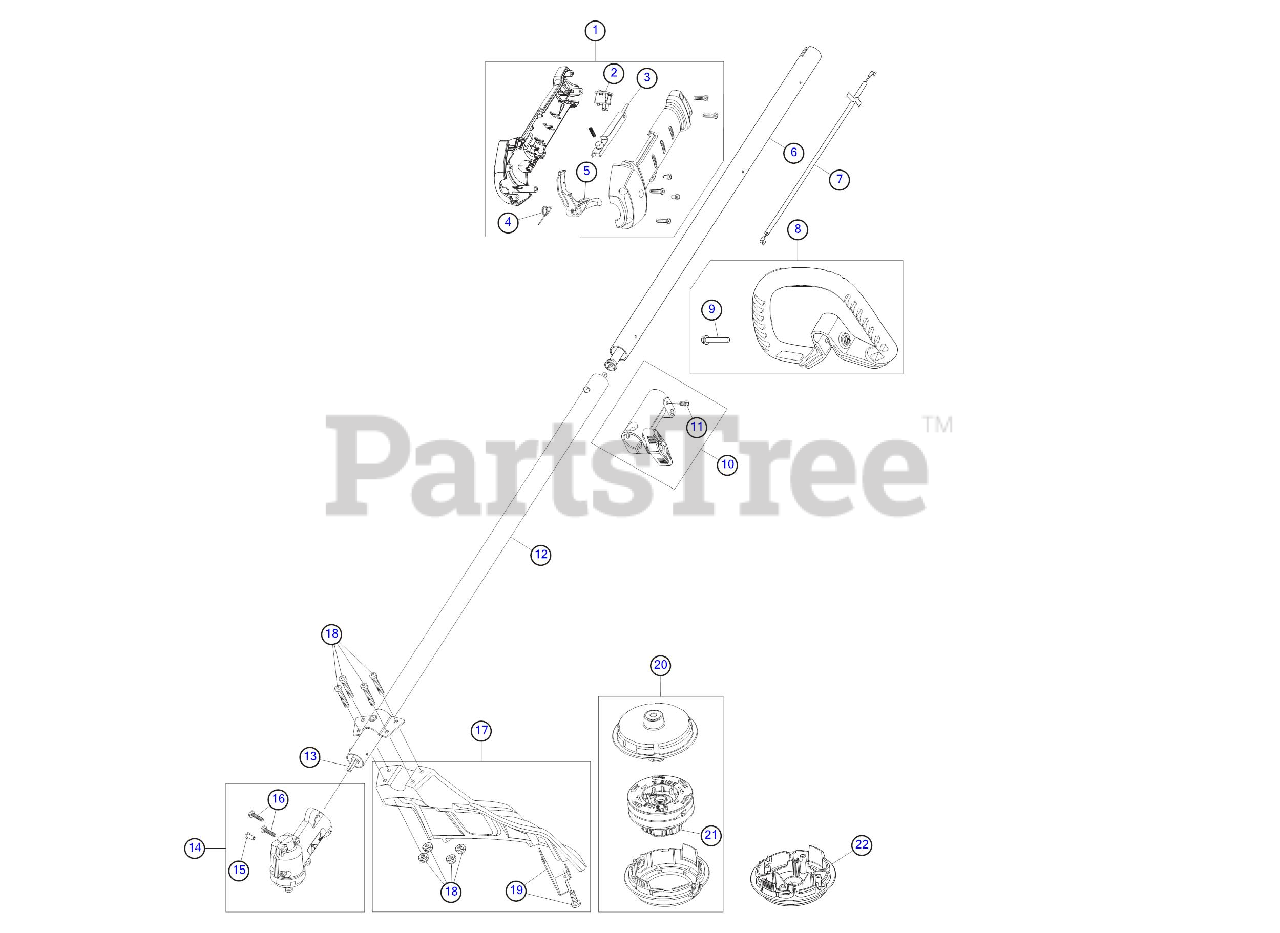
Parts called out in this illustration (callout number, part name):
1	Throttle Housing Assembly
2	Trigger Switch Assembly
3	Throttle Lock-out
4	Throttle Trigger Spring
5	Throttle Trigger
6	Upper Drive Shaft Assembly
7	Throttle Cable
8	D-Handle Assembly
10	Split Boom Coupler
11	Coupler Anti-Rotation Screw
12	Lower Drive Shaft Housing Assembly
13	Lower Flexible Drive Shaft
14	Gearbox Assembly
15	Gearbox Anti-Rotation Screw
16	Gearbox Mounting Hardware
17	Shield Assembly
18	Shield Mounting Screws and Nuts
19	Blade Assembly
20	Cutting Head Assembly
22	Cap Assembly (with Plug)
